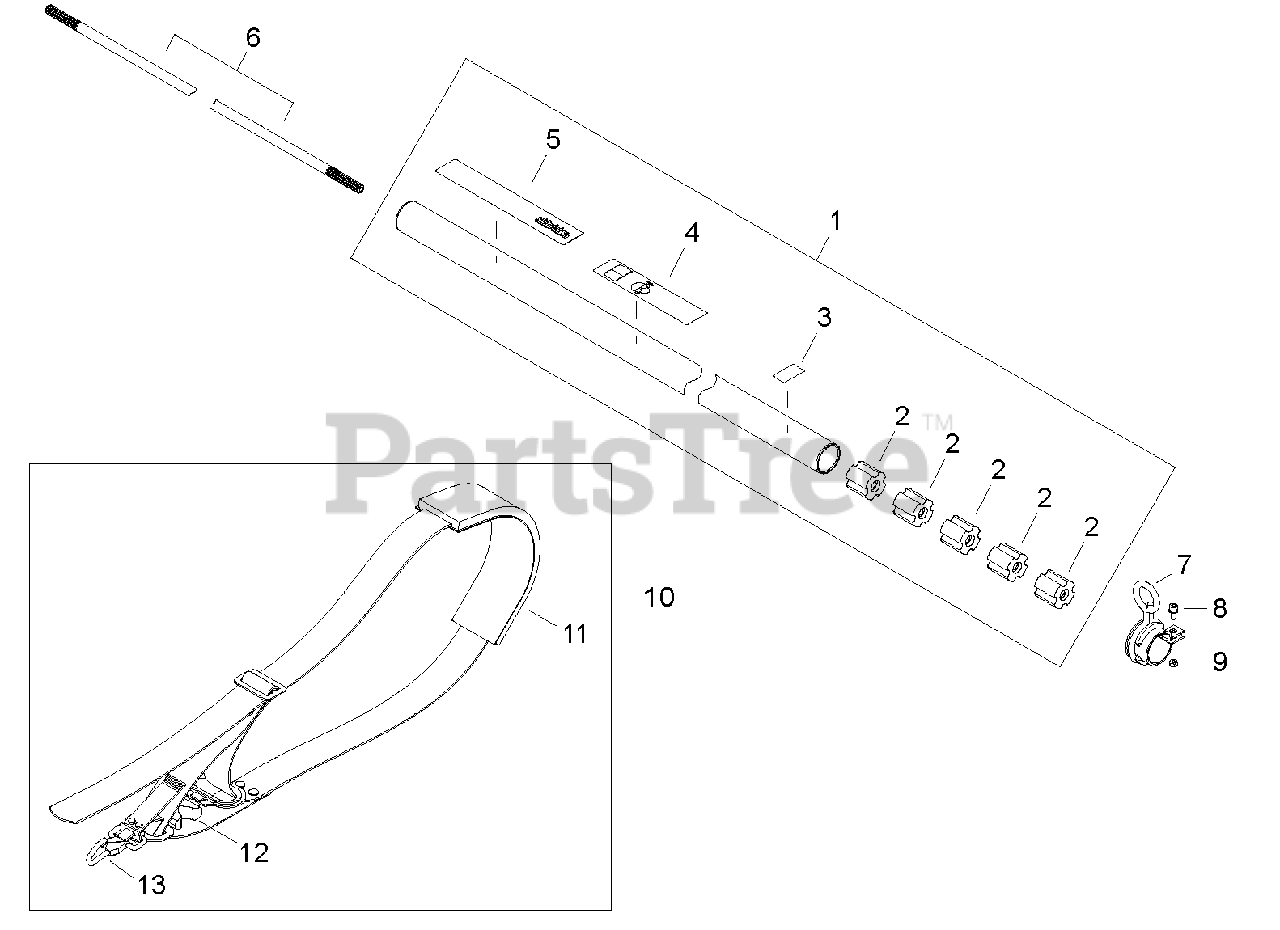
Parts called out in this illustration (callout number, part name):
1	MAIN PIPE ASSY
2	BUSHING
3	LABEL - INSTRUCTION
4	LABEL - CAUTION
5	LABEL - SHINDAIWA PROFESSIONAL
6	DRIVESHAFT
7	HANGER
8	SCREW - 5X12
9	NUT - 5
10	HARNESS ASSY
11	PAD, SHOULDER
12	CUSHION, HARNESS
13	HOOK
